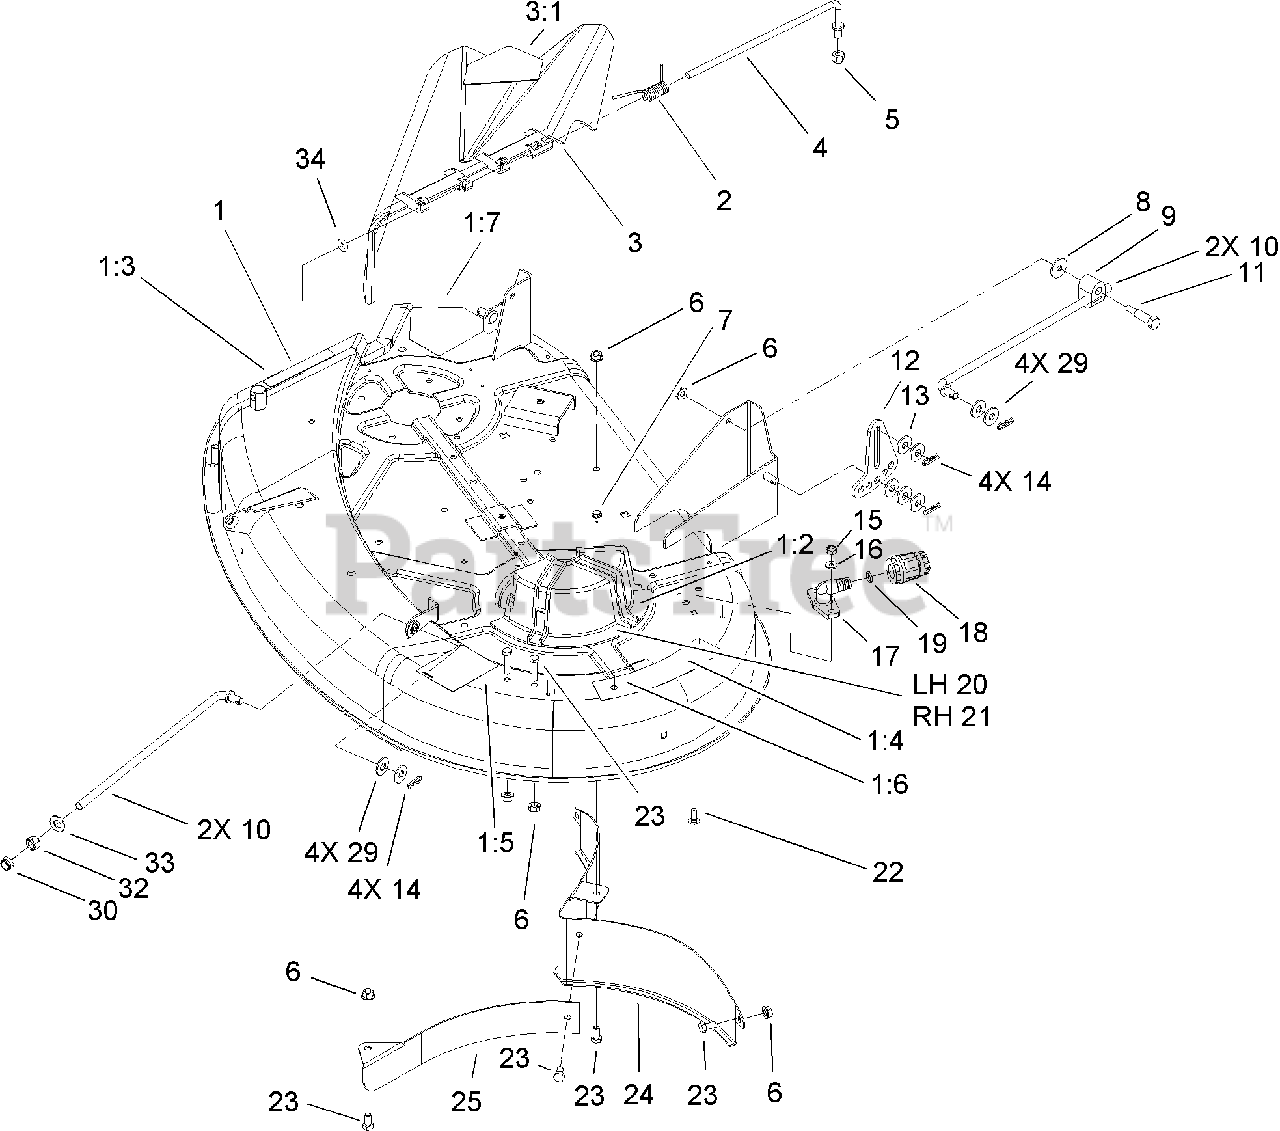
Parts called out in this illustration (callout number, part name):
1:2	DECAL-DANGER, SHIELD
1:3	DECAL-DANGER, DEFLECTOR
1:4	DECAL-DANGER
1:5	DECAL-ROUTING, BELT
1:6	RIVET-POP
1:7	DECAL-DANGER
3	DEFLECTOR ASM
3:1	DECAL-DANGER
4	ROD-PIVOT
5	NUT-LOCK, NI
8	WASHER-PIVOT
9	TRUNNION-HOC
10	ROD-HANGER
11	BOLT-SHOULDER
12	LINK-ADJUSTING, HOC
13	WASHER-HARDENED
14	PIN-HAIR
15	NUT-LOCK, NI
16	WASHER-FLAT
17	FITTING-WASHOUT
18	CONNECTOR-HOSE
20	GUIDE-BELT, LH
21	GUIDE-BELT, RH
22	SCREW-CARR
23	SCREW-HH
24	BAFFLE-REAR
25	EXTENSION-BAFFLE
29	WASHER-FLAT
30	NUT-LOCK, NI
32	NUT-HEX
33	WASHER-FLAT
